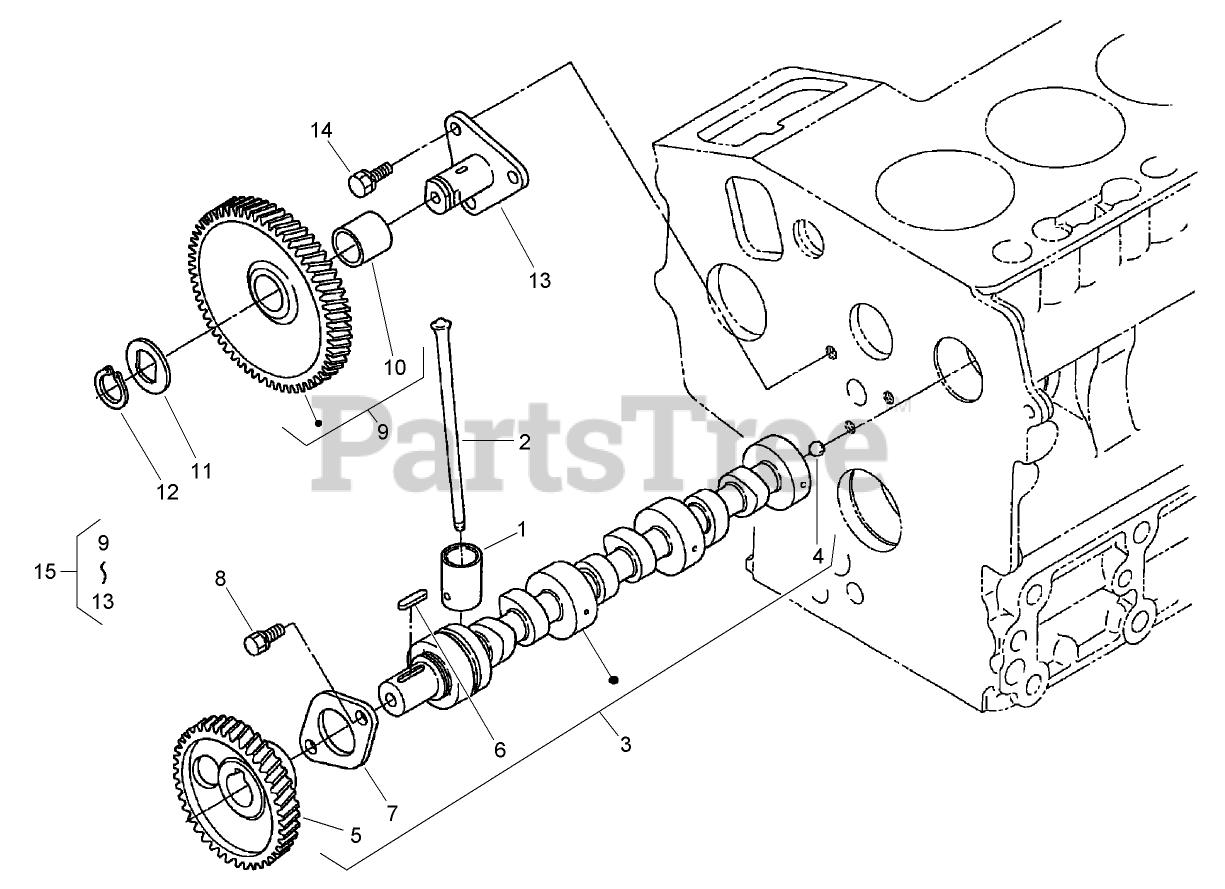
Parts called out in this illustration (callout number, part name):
1	TAPPET
2	ROD-PUSH
3	CAMSHAFT ASM
5	GEAR-CAM
6	KEY-FEATHER
7	STOPPER-CAMSHAFT
9	GEAR-IDLE
10	BUSHING
11	COLLAR-GEAR, IDLE
12	RING-SNAP
13	SHAFT-GEAR, IDLE
15	IDLE GEAR ASM
